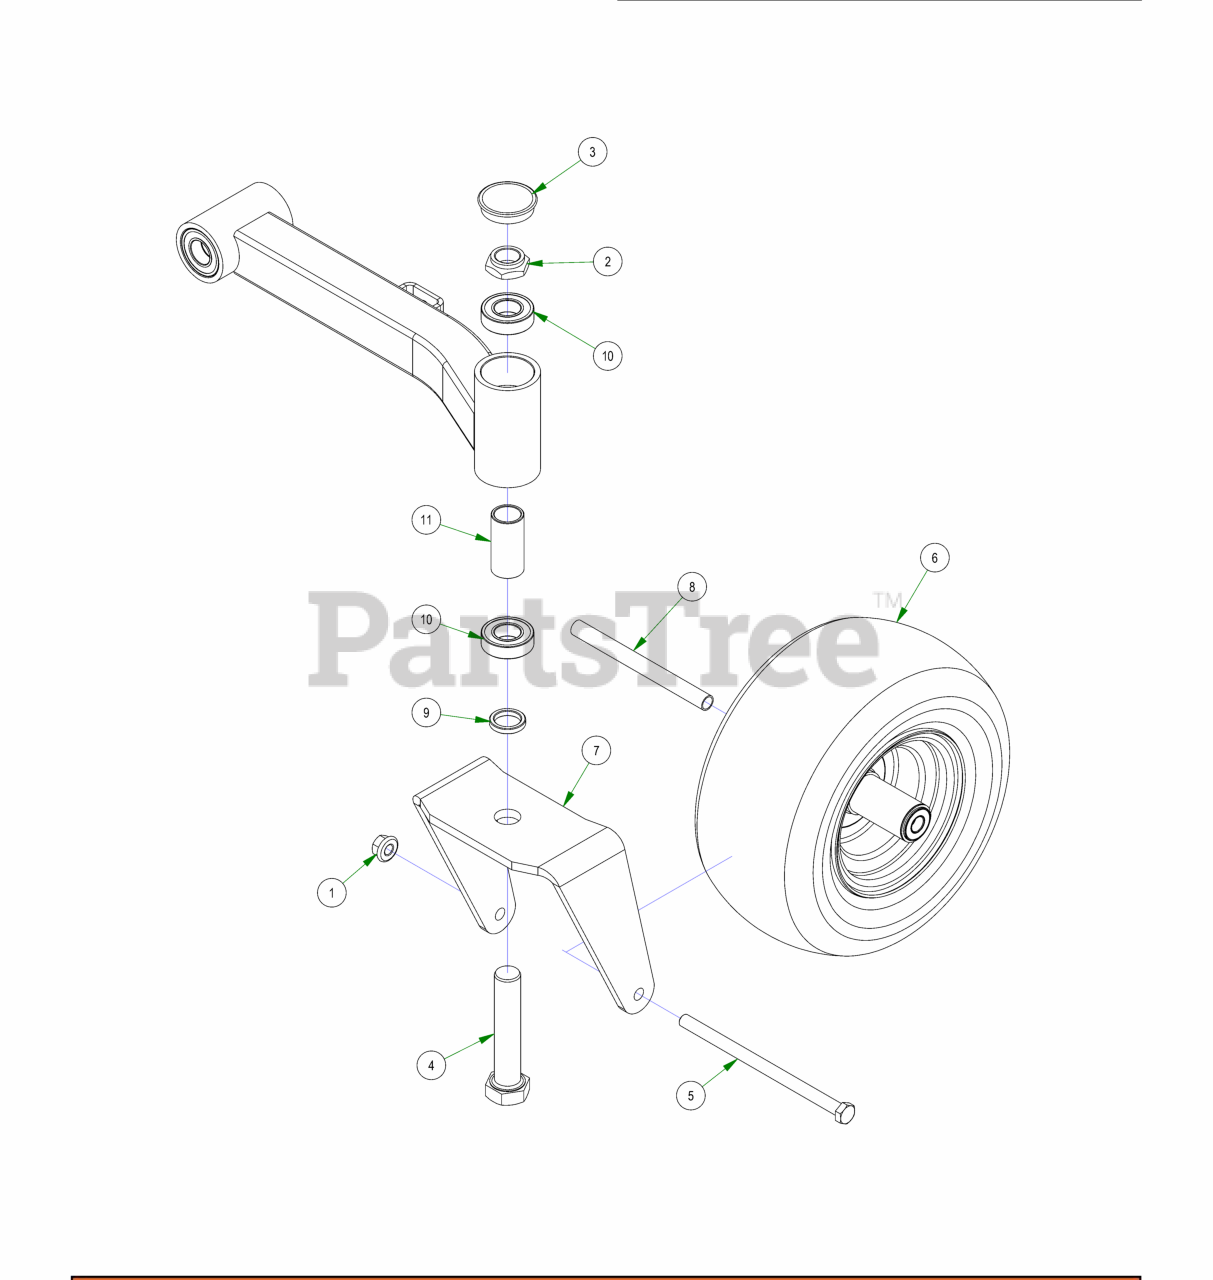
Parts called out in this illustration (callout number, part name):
1	1/2-13 NYLON INSERT FLANGE LOCKNUT ZINC
2	1"-14 NYLON INSERT JAM LOCKNUT ZINC
3	2017 Bearing Cover
4	1"-14 X 5 HEX CAP SCREW (GR.8) ZINC YELLOW
5	1/2-13 X 8-1/2 HEX CAP SCREW (GR.5) ZINC
6	13x6.5-6 Black Tire and Wheel Assembly
7	2017 ZT Front Fork
8	Front Wheel Spanner
9	Spacer, 1x1.375x.25
10	1641 BEARING W/2 CONTACT RUBBER SEALS
11	2016 Front Bearing Spacer
